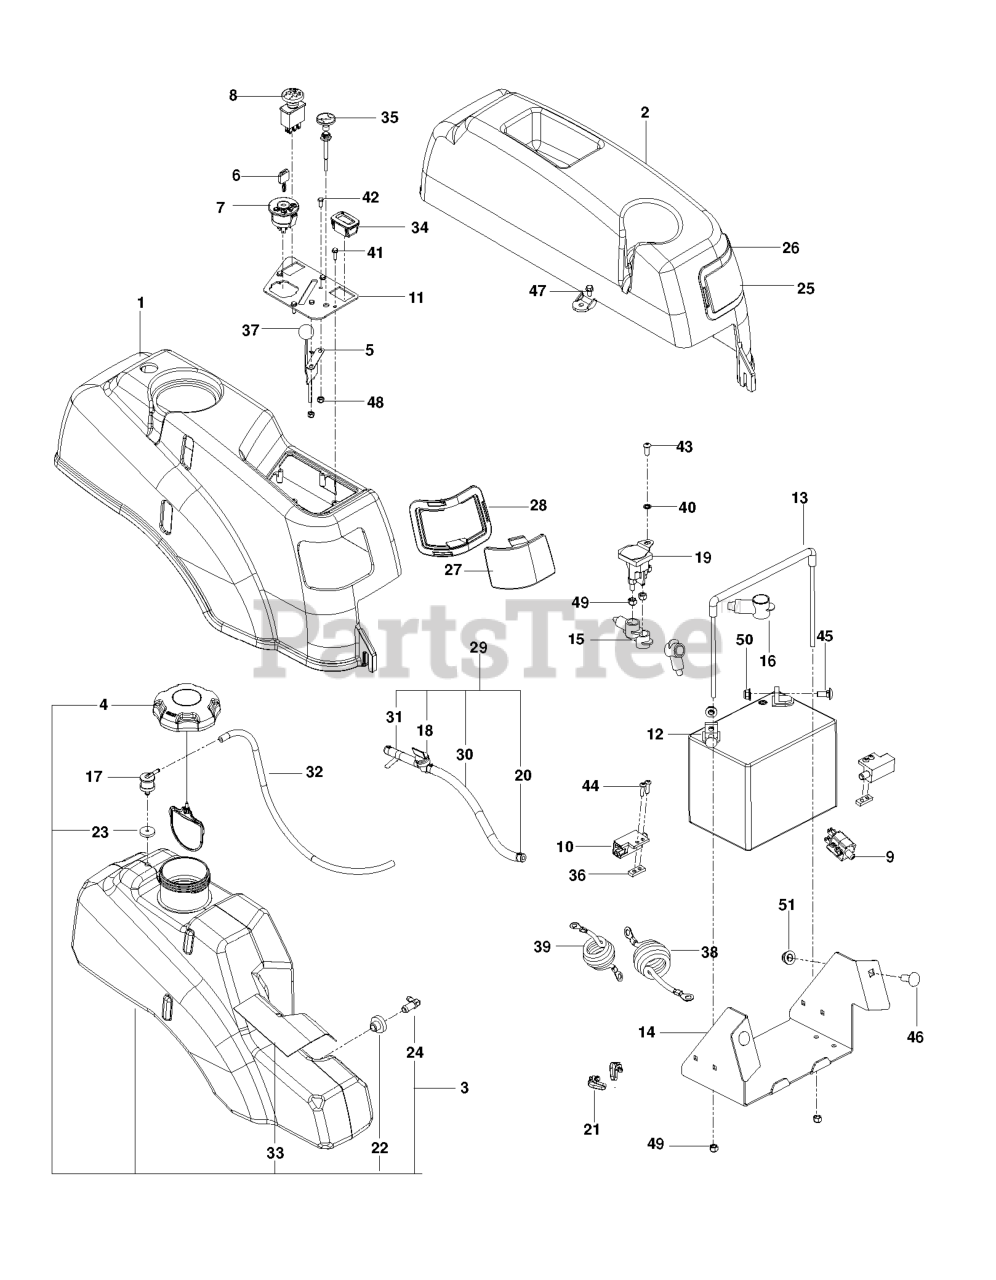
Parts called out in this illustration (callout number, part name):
1	FENDER RT, GRAY
2	FENDER, LT
3	TANK.FUEL.ASSEMBLY.LARGE
4	CAP, FUEL
5	THROTTLE CABLE
6	KEY MLD GEN DELTA
7	RP IGNITION SWITCH
8	RP SWITCH.PTO.8.TERMINAL.RED
9	SWITCH, BRAKE 3P
10	SWITCH INTERLOCKT
11	CONSOLE.PLATE.BLACK
12	BATTERY, 12 V 330 AMP
13	BATTERY TIE DOWN ASSEMBLY
14	BOX, BATTERY, BLACK
15	TERMINAL COVER-SM
17	VALVE.FUEL.CHECK
18	FUEL VALVE
19	SOLENOID.W/BRASS.PLUNGER
20	HOSE CLAMP
21	TIE WRAP, 8-3/8", W/CLIP
22	RUBBER GROMMET
23	GROMMET, CHECK VALVE
24	STEM, FUEL TANK
25	LENS, COLORED LEFT
26	LEFT HEADLIGHT RIM GREY
27	LENS, COLORED RIGHT
28	RT HEADLIGHT RIM GREY
29	ASSEMBLY, FUEL LINE, KAW
30	GAS LINE 10"
31	FUEL LINE 14"
32	HOSE, VAPOR 3/16 X 48"
33	SHIELD, HEAT
34	RP.GUAGE.SRVCMNDR.HRMTR.
35	CHOKE CABLE
36	TAPPED PLATE
37	SCREW #10 X 1/2 SELF TAPPING
38	CABLE POSITIVE, LONG
39	BATTERY CABLE, NEGATIVE
40	WASHER 1/4 INT TOOTH
41	SCR #10-12X3/4 HEX WAS HD ZD
42	HCS #10-24 X 1/2
43	SCR 1/4-20 X 5/8 BTN SKT HD ZD
44	SCR #10-24 X .75 SKT HD BLK
45	BOLT 5/16C X 3/4" CARRIAGE
46	RHSNB 3/8C X 1
47	BOLT 1/4-20 X 1/2 HWST
48	NUT 10-24 NYLOC
49	NUT.1/4-20.HEX.NYLOC.ZD
50	5/16-18 NYLOC FLANGE NUT
51	NUT 3/8-16 NYLOC
